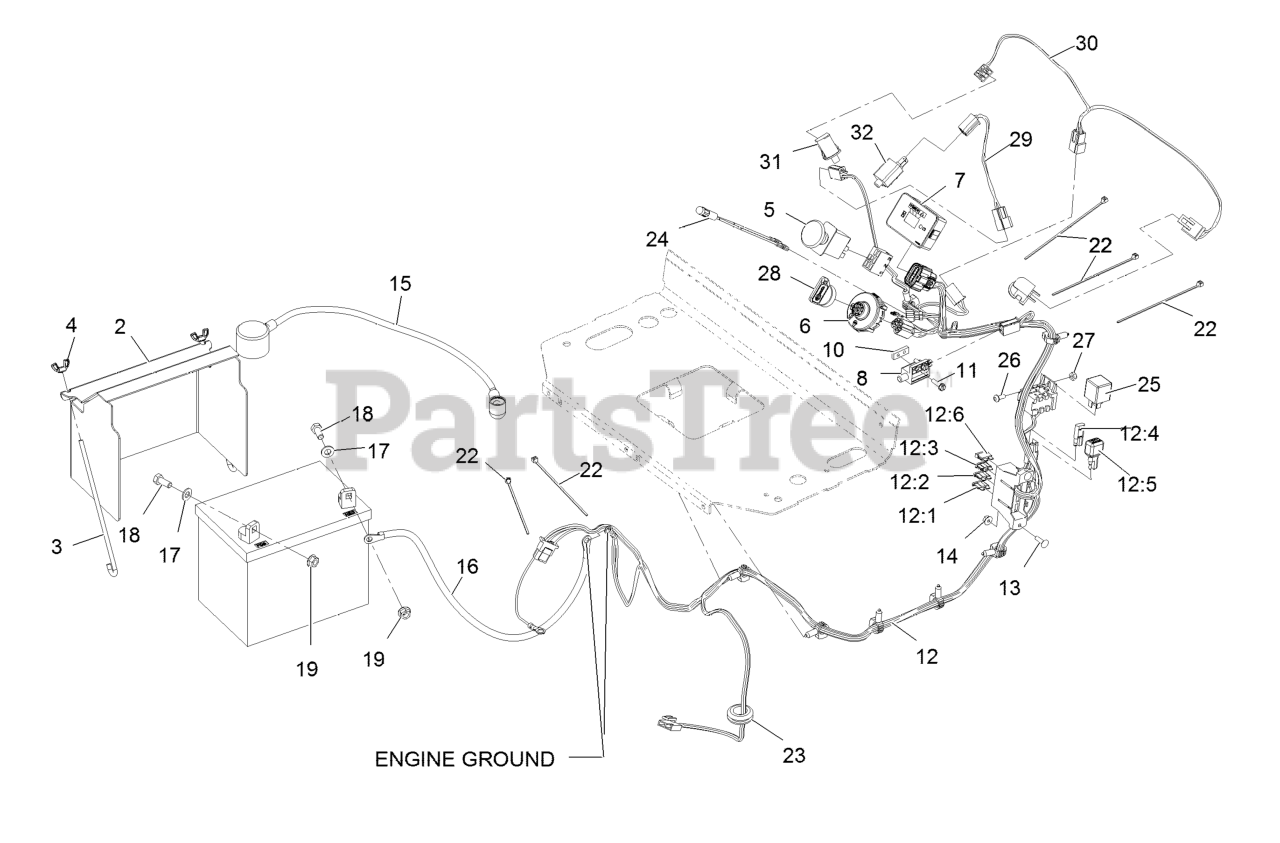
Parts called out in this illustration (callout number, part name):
2	COVER-BATTERY
3	BOLT-HOLDDOWN
4	WINGNUT
5	SWITCH-PTO, ON-ON
7	MODULE-HOUR METER
8	SWITCH-CLOSED, NORMALLY
10	PLATE-TAPPED
11	SCREW-HWH
12	HARNESS-WIRE, EFI
12:1	FUSE-BLADE, 30 AMP
12:2	FUSE-BLADE, 25 AMP
12:3	FUSE-BLADE, 10 AMP
12:6	FUSE-BLADE, 15 AMP
13	SCREW-CARR
15	CABLE-BATTERY, POSITIVE
16	CABLE-BATTERY, BLACK
17	WASHER-PLAIN
18	SCREW-HH
19	NUT-HHF, SMOOTH
22	TIE-CABLE
23	GROMMET
24	INDICATOR-LED, RED
26	SCREW-PPH
27	NUT-LOCK, NI
28	KEY-IGNITION
29	HARNESS-NEUTRAL
30	HARNESS-OPC
31	SWITCH-BAIL
32	SWITCH-OPEN, NORMALLY
